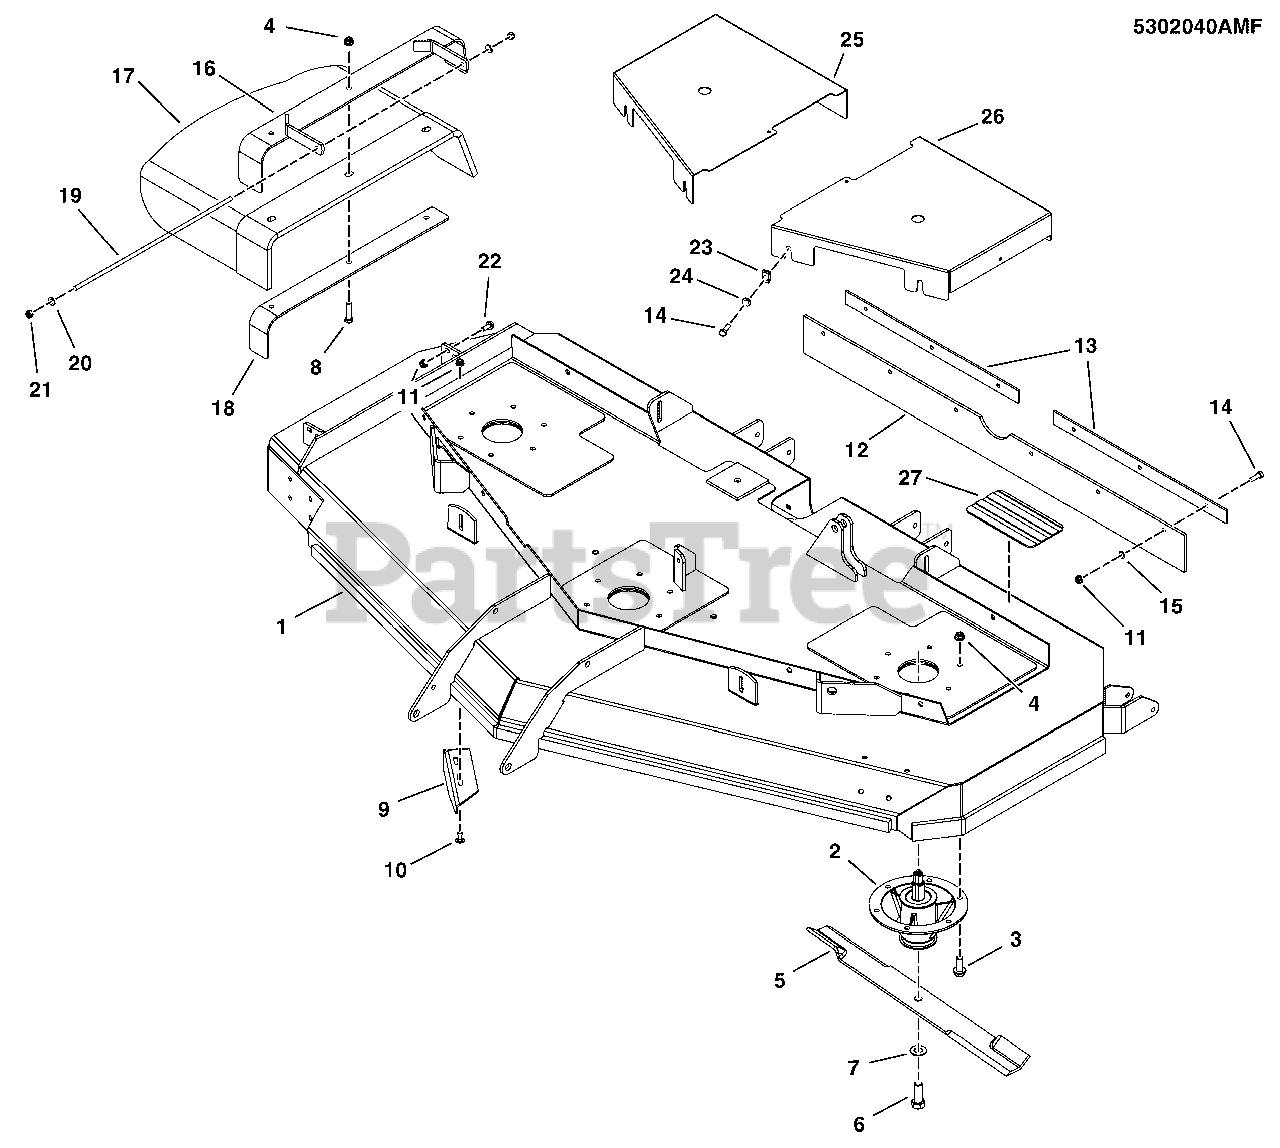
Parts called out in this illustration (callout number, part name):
1	DECK SHELL W/ DECALS, 72 - S800X
2	SPINDLE ASSM, CAST IRON 8.0-6 BOLT
3	BOLT, 3/8-16 X 1-1/4, FLANGE, GD 5, CZ
4	NUT, 3/8-16 HEX NYLOCK FLANGE
5	BLADE, 25 X 25 X 2.50, HIGH LIFT (SET OF 3)
5	BLADE, 25 X 25 X 2.50, HIGH LIFT
6	BOLT, 5/8-11 X 1-3/4 GD8
7	WASHER, 5/8 GRADE 8, YZ
8	BOLT, 3/8-16 X 1-1/2 GD5 YZ
9	PLATE, DEFLECTOR, 72 - BLK
10	BOLT, 5/16-18 X 3/4, CARRIAGE
11	NUT, 5/16-18 HEX NYLOCK FLANGE
12	FLAP, STRIPER, 72 DECK
13	PLATE, SUPPORT, 72, S800X - RED
14	BOLT, 5/16-18 X 1 GD5 YZ
15	NUT, Push On, 5/16
16	WELD, FRAME, CHUTE, 72 - BLK
17	CHUTE, DISCHARGE, BEND RUBBER (SV)
18	SUPPORT, DICHARGE CHUTE, 61/72 - BLK
19	ROD, MOUNT, CHUTE, 72, CZ
20	WASHER, 5/16 SAE
21	NUT, 5/16-24 HEX NYLON LOCK
22	SCREW, 5/16-18X0.750, GR5, WHIZ-LOCK, ZC
23	BODY CLIP, 5/16-18-7GA MATERIAL
24	WASHER, 5/16 GD.9 FLAT
25	GUARD, DECK - RH - RED
26	GUARD, DECK - LH - RED
27	SAFETY WALK, 4.00 X 7.50
